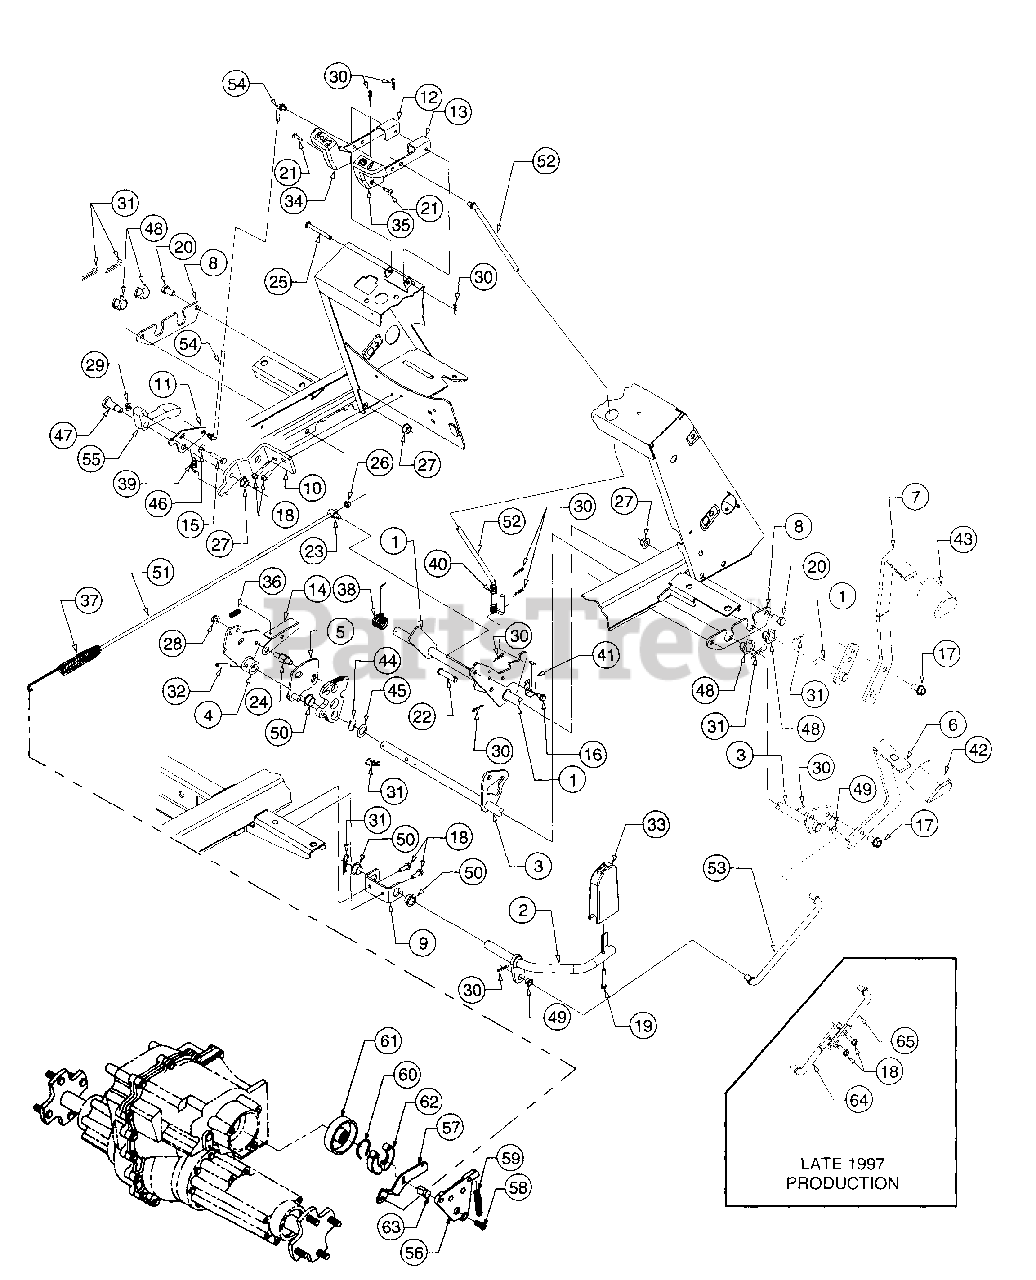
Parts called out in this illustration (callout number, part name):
1	Shaft Assy, Brake
4	Cam Assy, Control
5	Plate Assy, Disengagement
6	Pedal, Forward
7	Pedal, Brake
8	Plate, Bearing Mounting
10	Bracket, Cruise
11	Plate, Rod Adjustment
15	Screw, Hex Cap, 1/4-20 x 1.25
16	Screw, Hex Wshr Tap 1/4-20 x .5
17	Screw, Hex Wshr Tap 3/8-16 x .75
18	Screw, Hex Wshr Tap 1/4-20 x .75
19	Screw, Truss Mach, #12 x 1.5
20	Screw, Hex Cap, 3/8-16 x .75 GR5
21	Screw, Phil Hd Pan, #10-24 x .75
22	Pin, Clevis, 3/8 x 1.62
23	Ferrule, Adjustment, 1/4-20 Thrd
24	Stud, Actuator
25	Pin, Clevis, .25 x 2.38 Lg
26	Nut, Hex Sems, 1/4-20
27	Nut, Hex Flange Lock, 3/8-16
28	Nut, Hex Flange Lock, 5/16-18
29	Nut, Hex Flange Lock, 1/4-20
30	Pin, Int Cotter, 5/16 Dia x 1.12 Lg
31	Pin, Int Cotter, 3/8 Dia x 1.62
32	Pin, Spiral Spring, 1/4 x 1.5
33	Pedal, Reverse
34	Knob, Cruise
35	Knob, Brake Lock
36	Spring Extension .38 OD x 2.1
37	Spring, Extension
38	Spring, Torsion
39	Spring, Ext, .437 OD x 1.32
40	Spring, Compression, .50 x 2.23
41	Spring, Switch Actuator
42	Pad, Forward Foot Control
43	Pad, Brake Foot
44	Washer, Wave, .625 x .885 x .015
45	Washer, Flat, .635 x 1.0 x .020
46	Washer, Flat, 1/4 x .63 x .051
47	Shoulder Bolt, .50 OD x .840
48	Bearing, Hex Flange Split
49	Bearing, Flange, .375 x .58 x .25
50	Bearing, Flange, .626 x .93 x .344
51	Rod, Brake
52	Rod, Parking Brake
53	Rod, Connecting
54	Rod, Cruise
55	Latch, Cruise
56	Plate, Brake
57	Arm, Brake
58	Screw, Low Hd Cap, 3/8-16 x .75
59	Spring, Compression
60	Spring, Brake
61	Drum, Brake
62	Shoe, Brake
63	Actuator, Brake Shoe
64	Rod, Rear Connecting
65	Rod, Front Connecting
